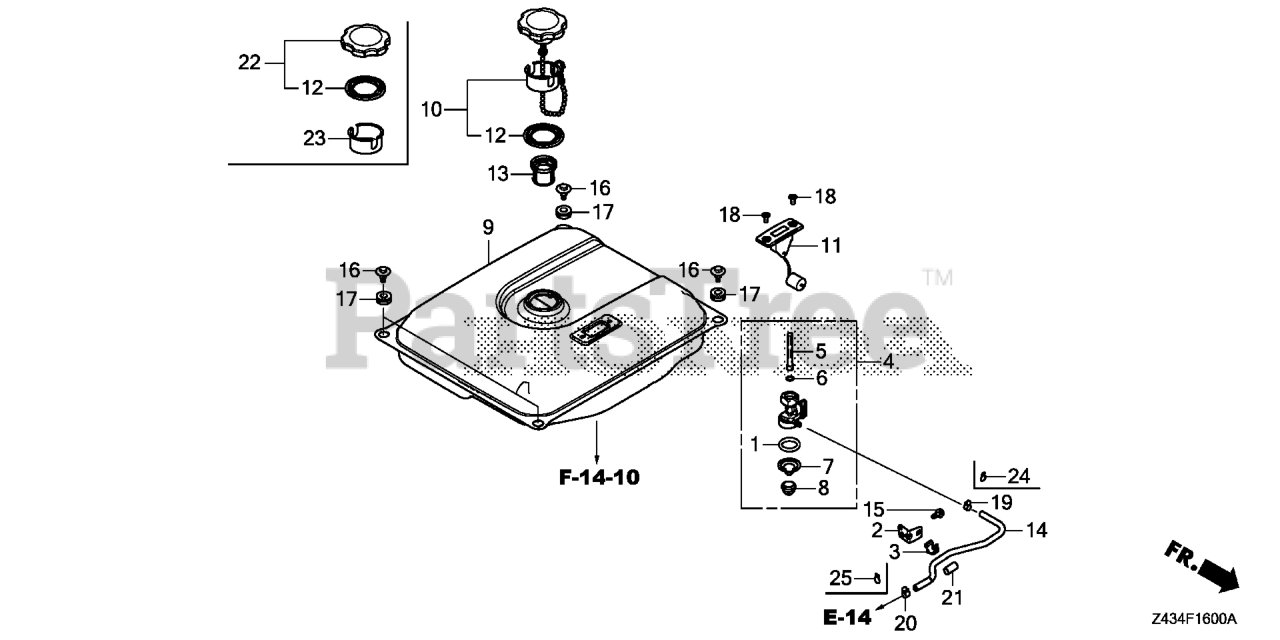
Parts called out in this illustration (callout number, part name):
2	BRACKET, FUEL TUBE
3	CLIP, TUBE
4	PETCOCK ASSY.
5	FILTER, FUEL
6	SEAL, PETCOCK
7	FILTER, CUP
8	CUP, FUEL STRAINER
9	TANK, FUEL *NH105* (MAT BLACK)
10	CAP, FUEL FILLER
11	METER ASSY., FUEL
12	GASKET, FUEL FILLER CAP (39X62X3) (TOUYOUSYA)
13	FILTER ASSY., FUEL
14	TUBE, FUEL TANK (FKM)
15	BOLT, FLANGE (6X12) (CT200)
16	BOLT, SPECIAL (6MM)
17	RUBBER, TANK CUSHION
18	SCREW, FLAT (5X10)
19	CLIP, TUBE (D8)
20	CLIP, TUBE (D8.5)
21	BULK HOSE, VINYL (9X11X3000) (9X11X150)
